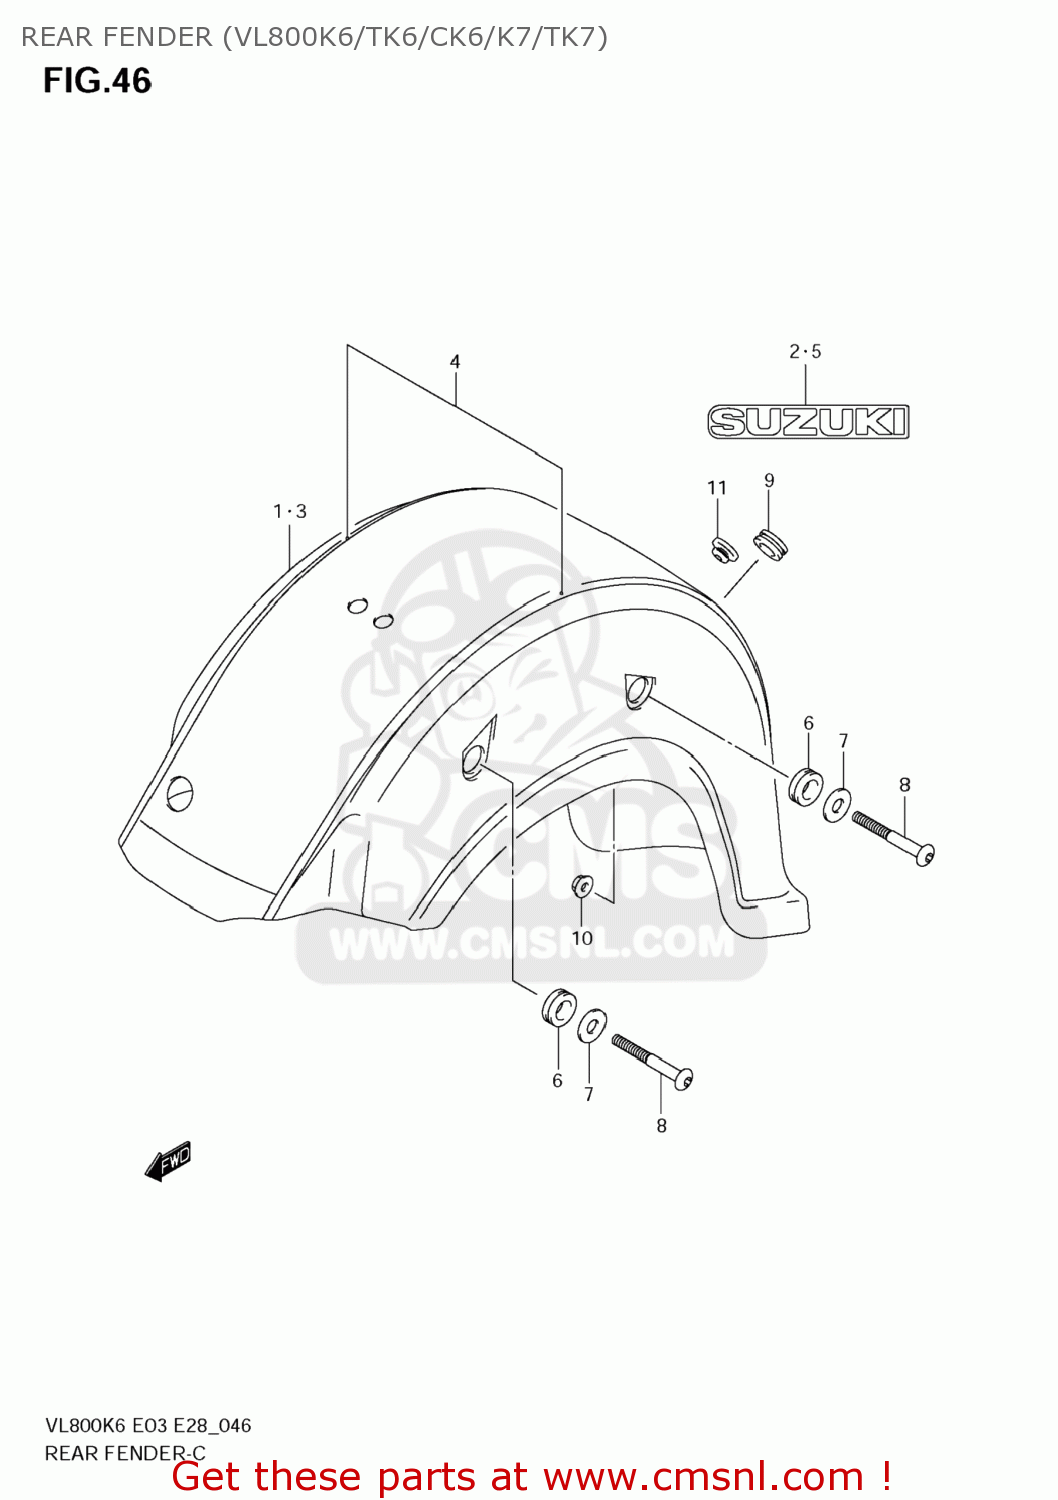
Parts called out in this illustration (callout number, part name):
1	FENDER,RR
2	EMBLEM,SUZUKI
3	FENDER,RR
4	TAPE SET,RR FENDER
5	EMBLEM,SUZUKI
6	CUSHION,FRAME COVER UPR RR
7	WASHER(15.5X26X2.3)
8	BOLT,RR FENDER
9	CUSHION
10	NUT
11	CUSHION
